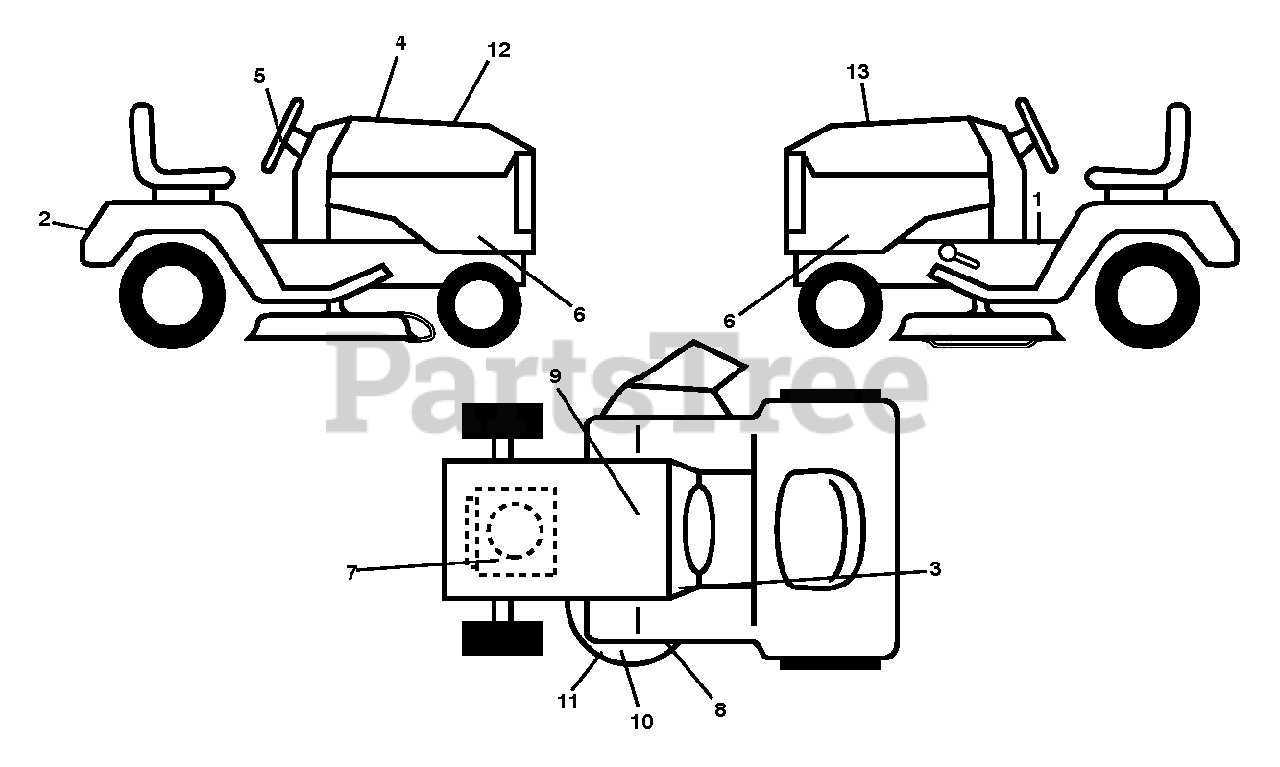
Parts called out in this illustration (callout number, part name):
1	DECAL.FNDR.WARN.SMARTIGN.
3	DECAL SNOWFLAKE
4	DECAL.RPL.BSM49.PROF.TGW.54.G7
6	DECAL.SDPNL.STEALTH.BRIGGS.BLK
7	DECAL.ENG.BS.JONS.27HP.382012
8	Mower Schematic Decal, 48/54 Prem
9	DECAL BTRY SYMBOLS
10	Keep Hand Away Warning Decal
11	Mower Caution Tension AR Decal
12	DECAL.HOOD.STEALTH.RH.2754GTHI
13	DECAL.HOOD.STEALTH.LH.2754GTHI
